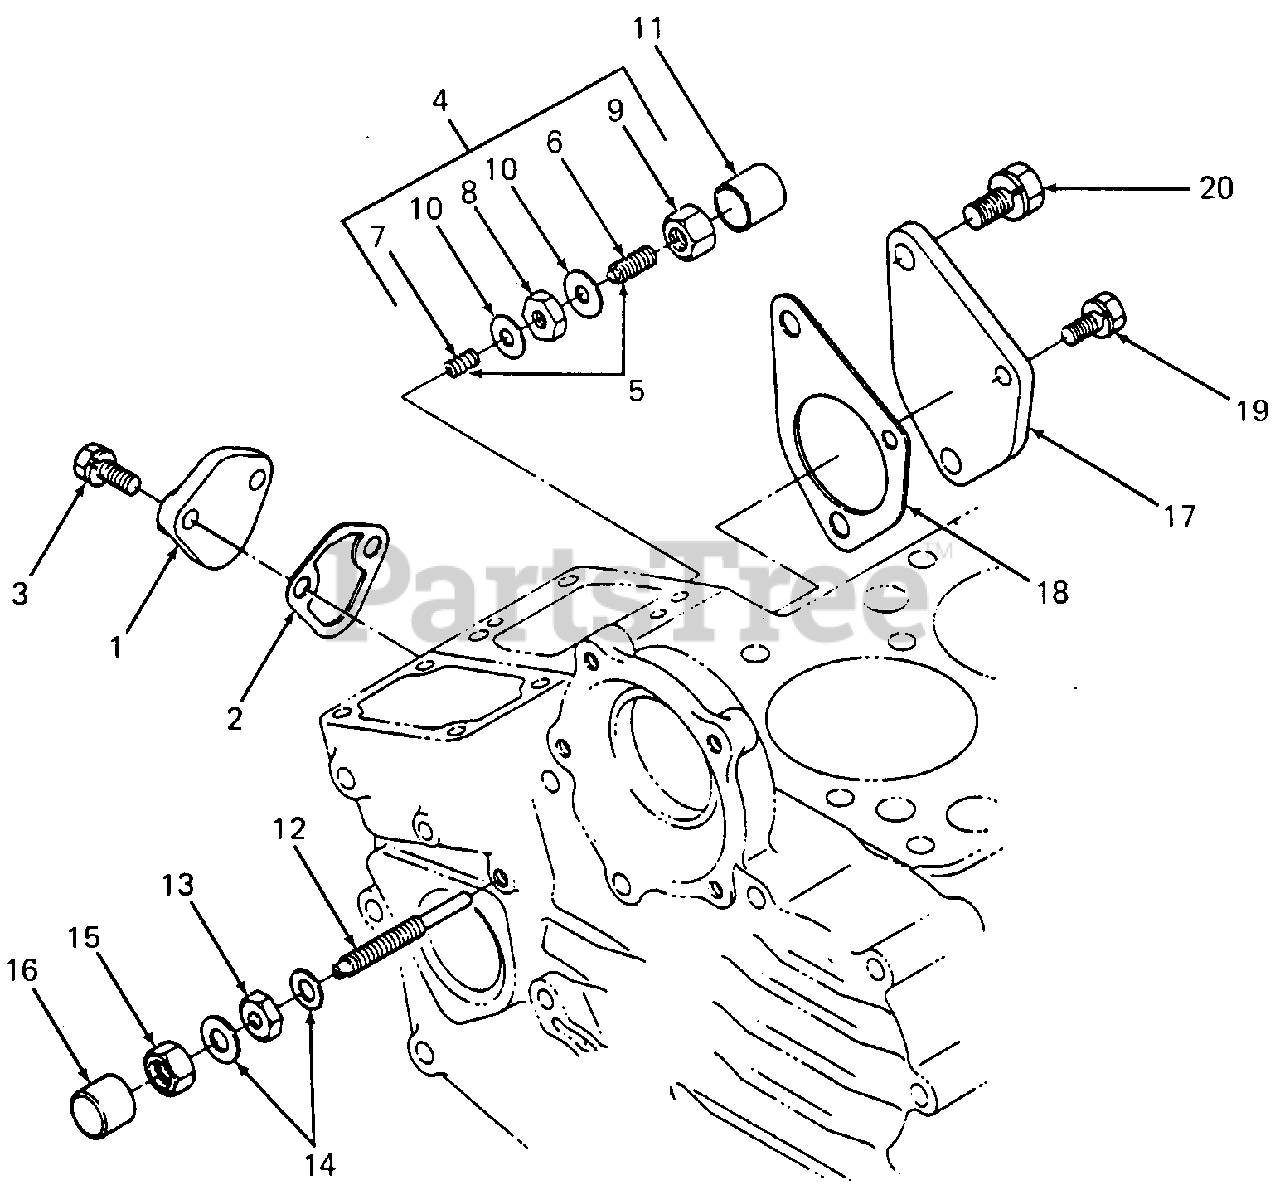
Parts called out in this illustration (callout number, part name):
3	Screw, Hex Cap w/Washer
4	Bolt Assy, Idling
5	Bolt Assy, Adjusting
12	Bolt, Adjusting
19	Screw, Hex Cap w/Washer
20	Screw, Hex Cap w/Washer
